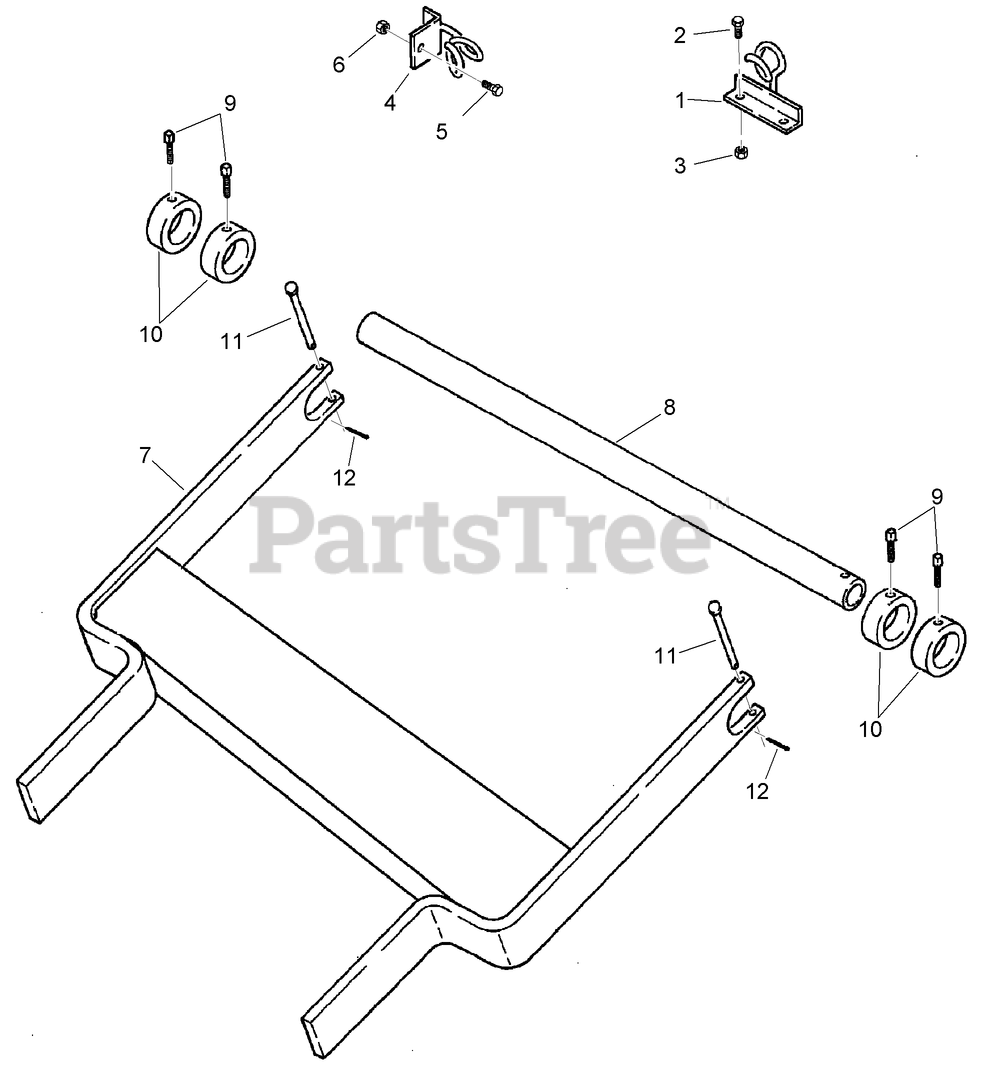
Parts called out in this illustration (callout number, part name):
1	GUIDE - Cable, Front, Mounts to Hood
3	NUT-Prev Trq 5/16 GRA CAD NONDIR
4	GUIDE - Cable, Rear, Mounts to ROPS
5	SCREW-HH
6	NUT
7	WELDMENT - Reel Carrier
8	PIPE - Reel Carrier
9	SCREW - Set, Square Head, 3/8 NC x 1 inch, Cup Point
10	COLLAR - Stop
11	PIN-CLEVIS
12	PIN-Cotter, 1/8 x 3/4 inch
